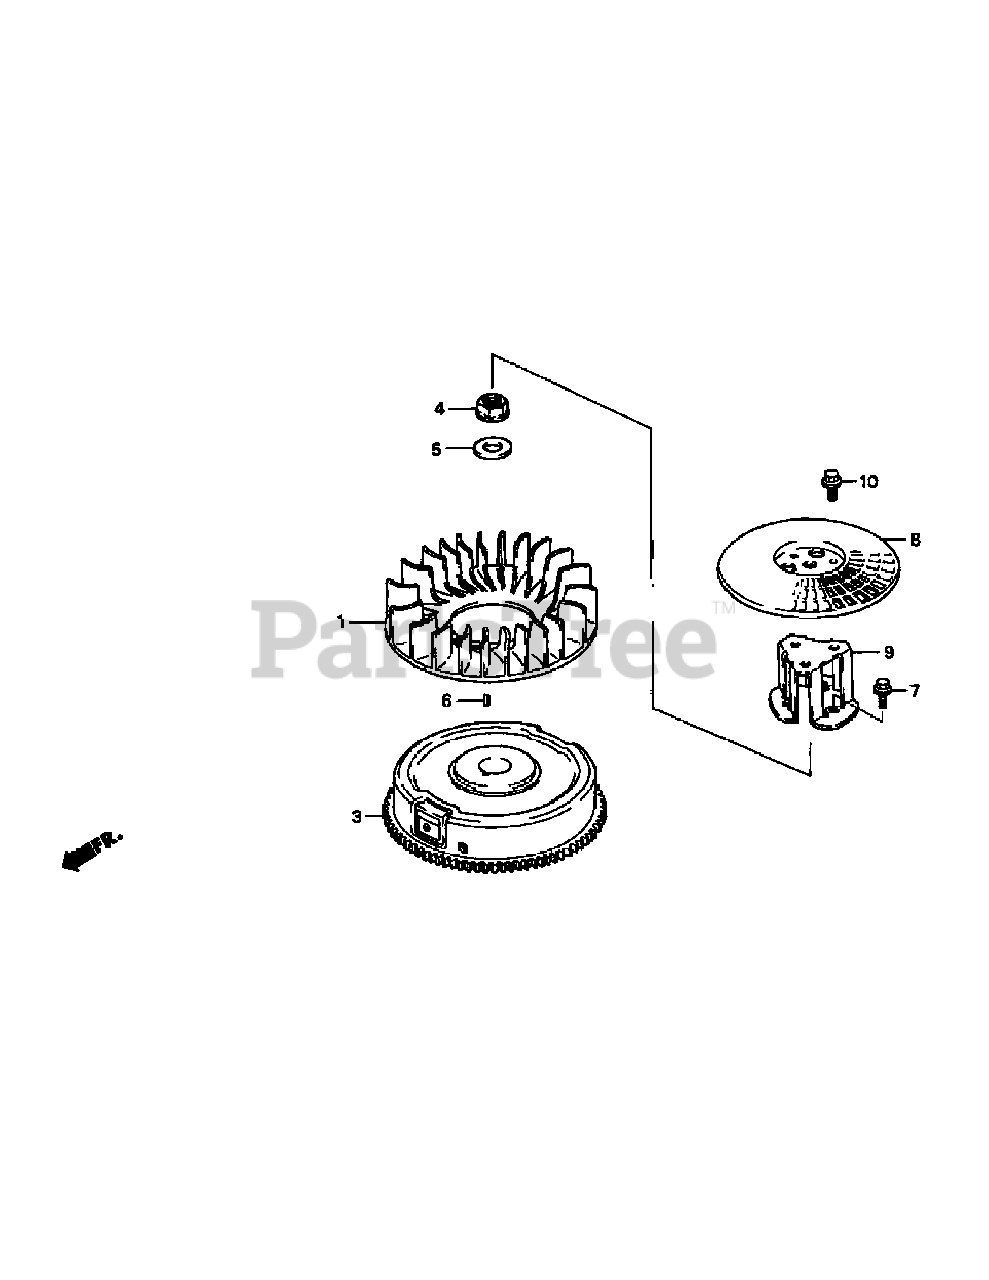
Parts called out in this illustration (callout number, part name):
1	Cooling Fan
4	Flange Nut (20mm)
5	Washer (20mm)
6	Special Woodruff Key (25x18)
7	Flange Bolt (8x16)
8	Screen Grid
9	Screen Grid Holder
10	Flange Bolt (6x12)
